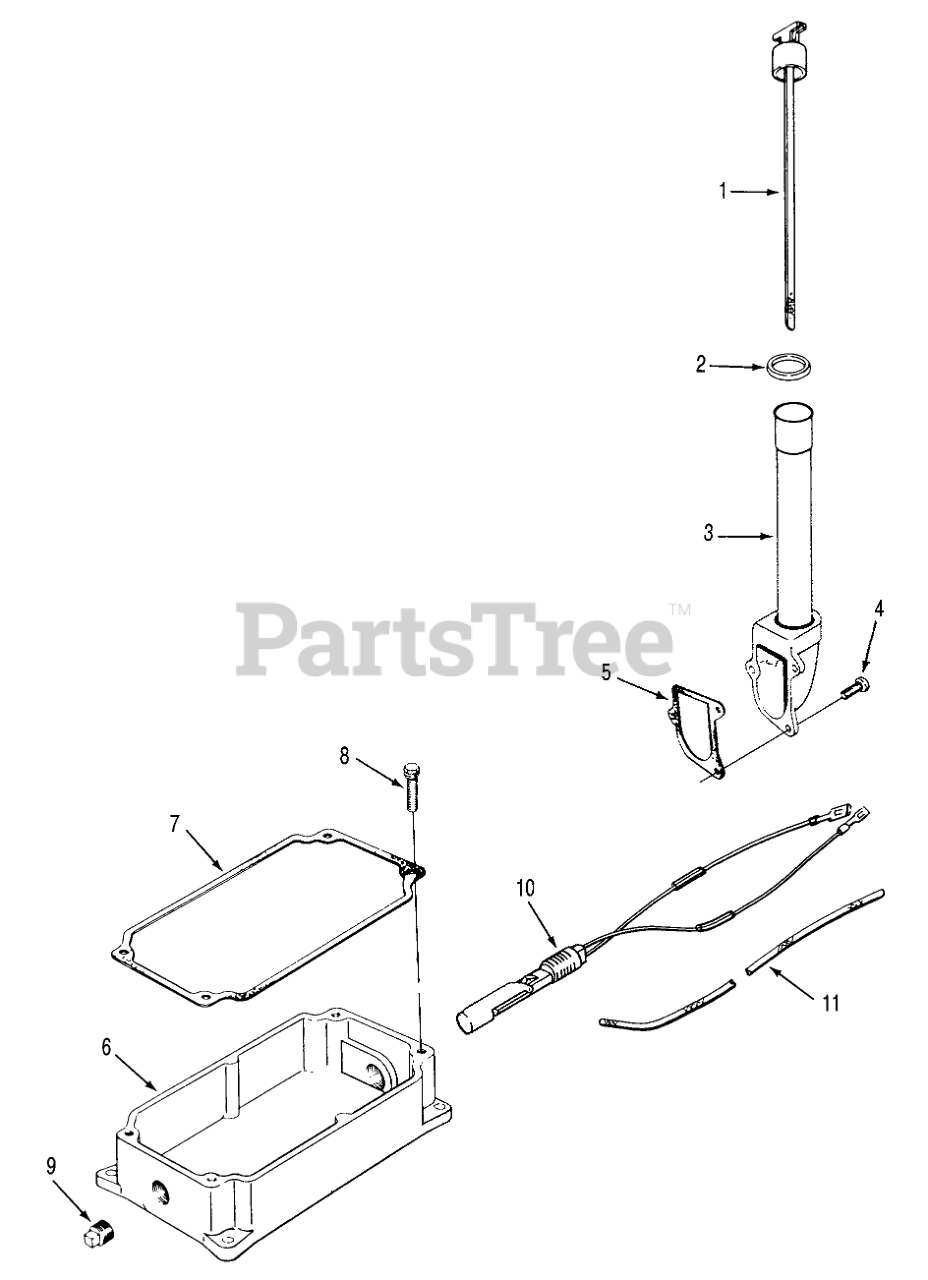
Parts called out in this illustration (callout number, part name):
1	Dipstick
2	O-Ring
3	Adapter-Oil Fill
4	Screw
5	Gasket
6	Oil Pan
7	Gasket
8	Screw
9	Plug
10	Float Switch Kit (Includes Items 12 & Decal)
11	Sleeving
